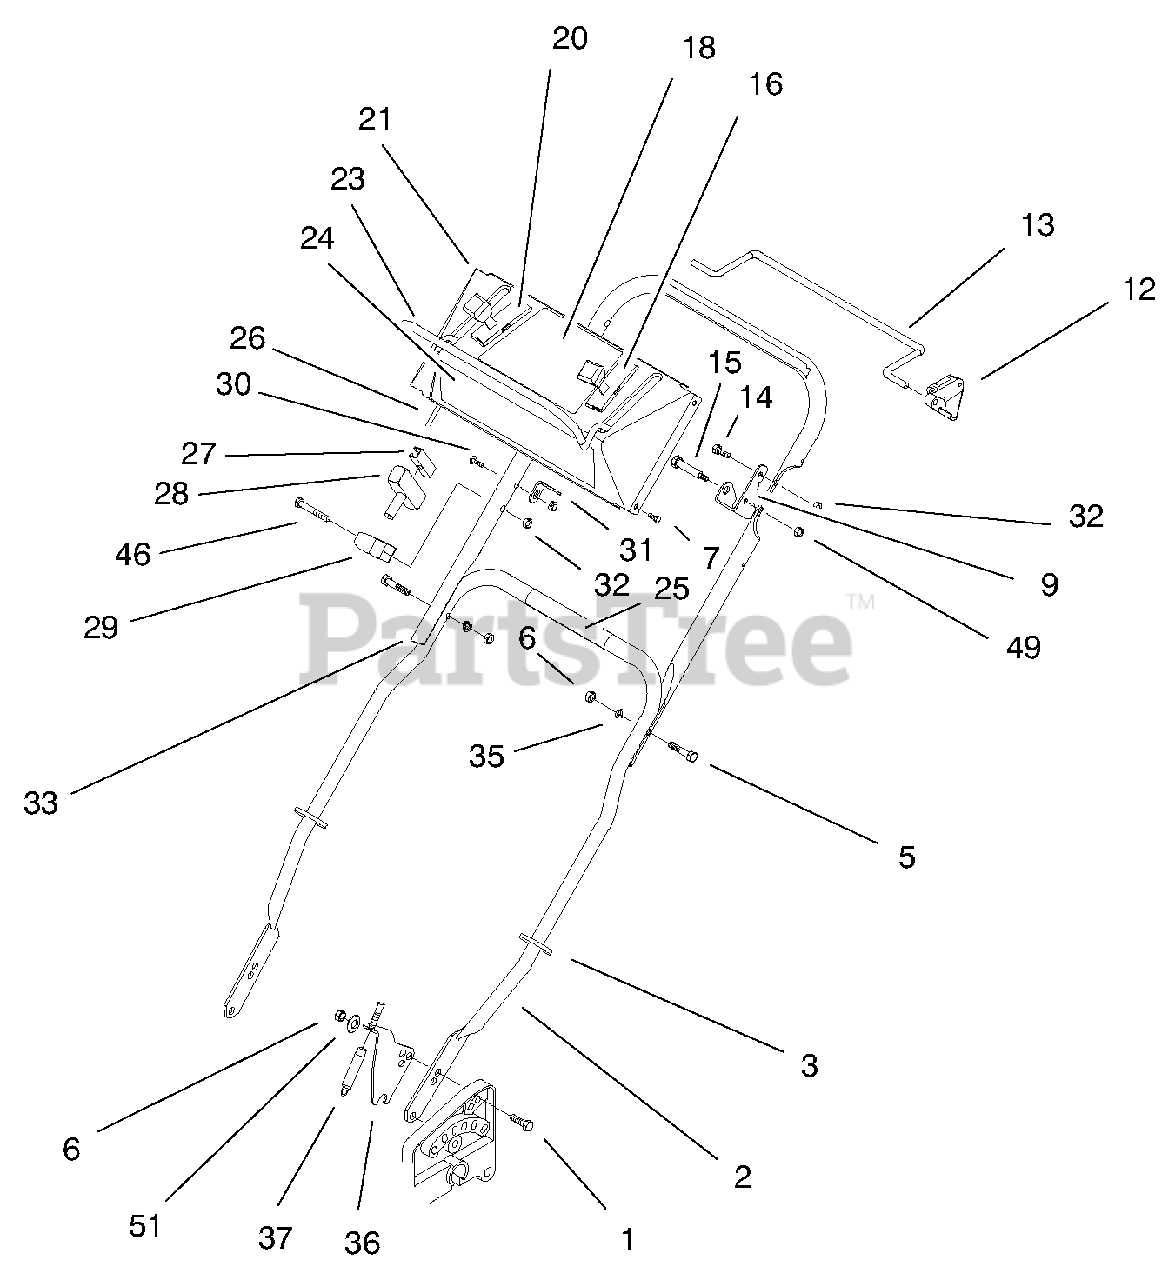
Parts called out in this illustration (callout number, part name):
1	Bolt-CARR
2	Handle Section-Lower
3	Tie Strap
5	Screw-HH
6	Nut-Lock
7	Screw-Phil
9	Bail Stop Bracket
12	Stop-Pivot
13	Bail-Sp Control
14	Screw-HH
16	Throttle Cable
18	Decal-Control Panel
20	Control-Speed
21	Panel-Control
23	Engine Control Bail
24	Decal-Console
25	Decal-Operation
26	Cable-Control
27	Clip-Rope
28	Handle-Starter
29	Guide-Rope
30	Handle Screw
31	Bracket-Cable Anchor
32	Nut-Lock
33	Handle-Upper
36	Bracket-Traction Cable
46	Bolt-Hex
49	Nut-Lock
51	Washer-Flat
